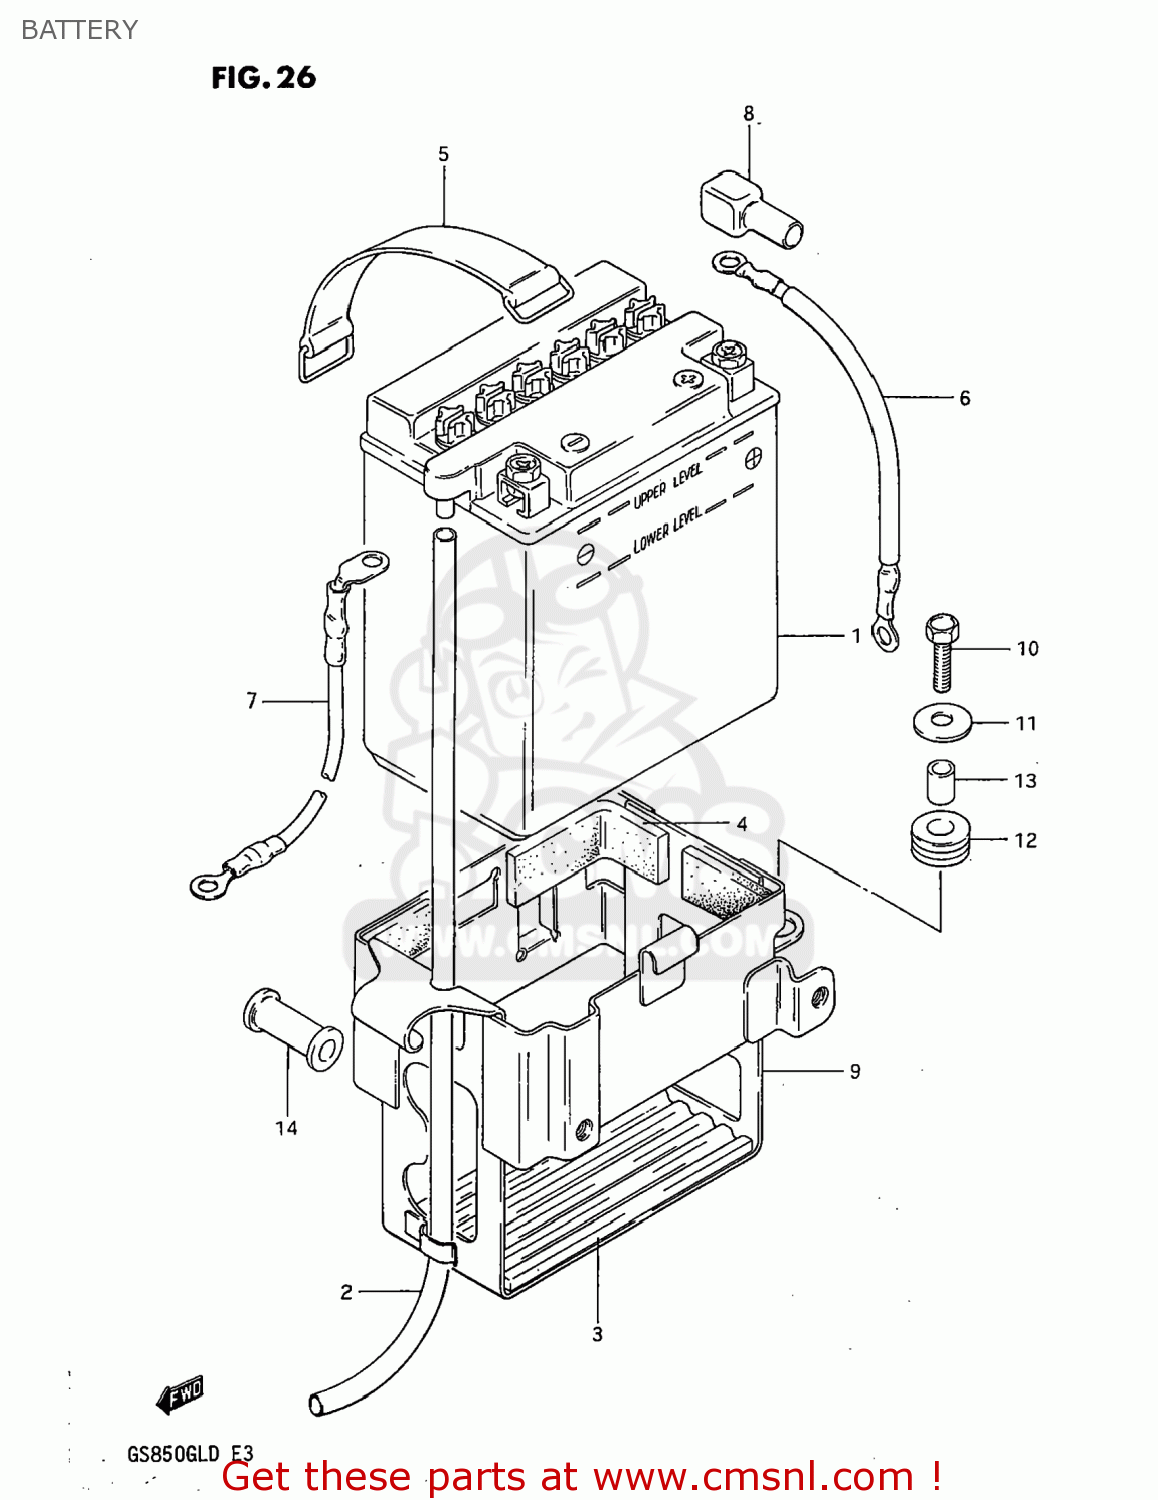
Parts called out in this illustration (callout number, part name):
1	BATTERY ASSY (12V)
2	HOSE,BATTERY EXHAUST
3	PROTECTOR,BATTERY
4	PROTECTOR(20X90)X4
5	BAND
6	WIRE,BATTERY PLUS
7	LEAD WIRE,BATTERY(-)
8	CAP,TERMINAL
9	HOLDER,BATTERY
10	BOLT, UPPER
11	WASHER(6,5X22X1.6)
12	CUSHION
13	SPACER(6.2X8.3X5.7)
14	CUSHION
